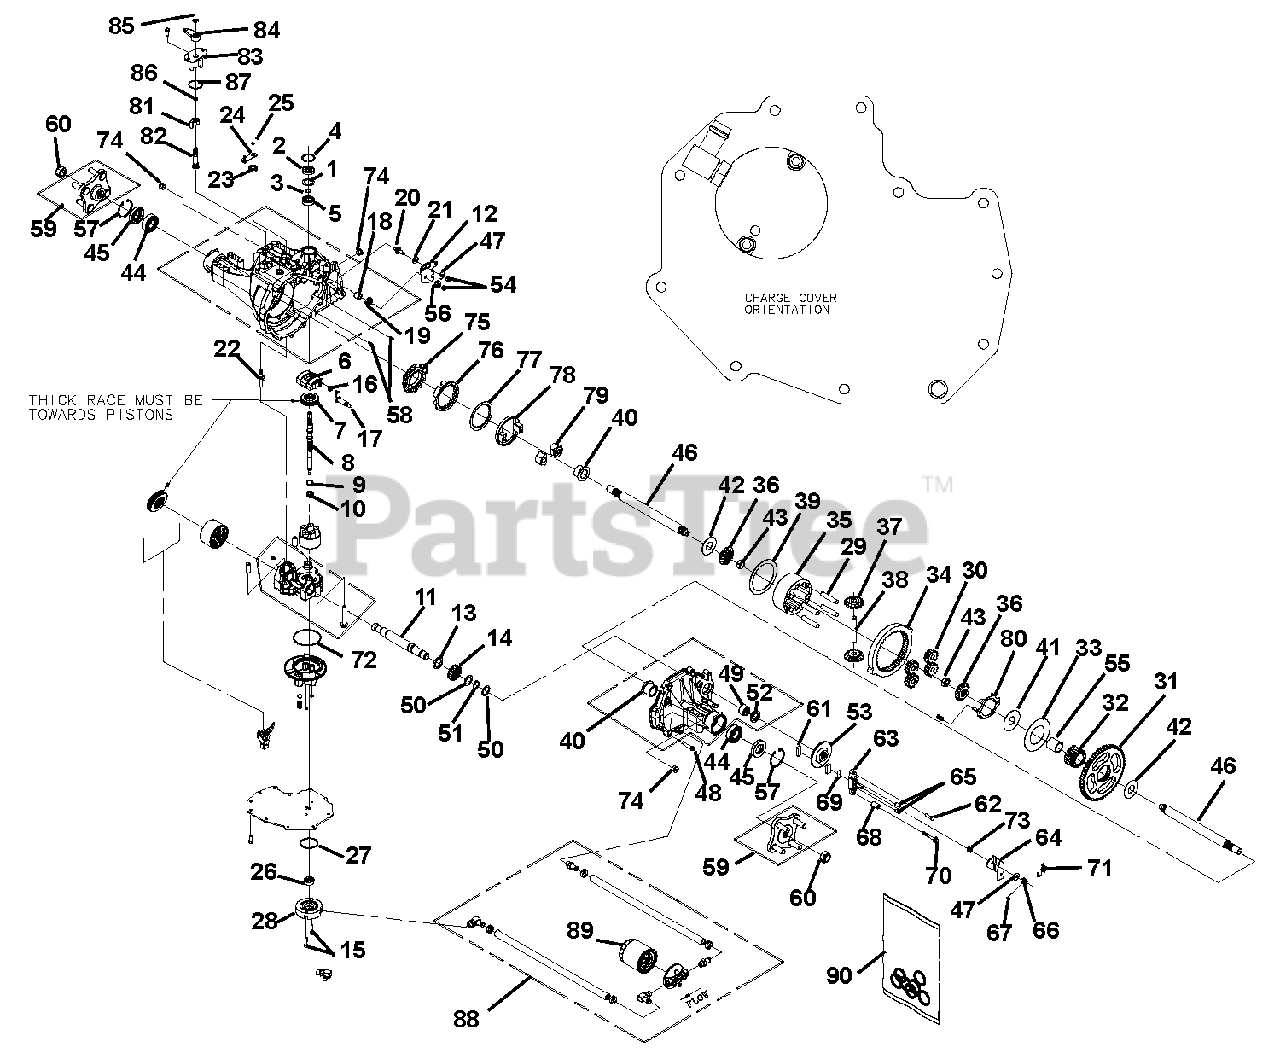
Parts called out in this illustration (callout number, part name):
1	Spacer, .98 x 1.37 x .04
2	Seal, Lip 15 x 35 x 7
3	Ring, Wire Retaining
4	Ring, Retaining
5	Bearing, Shaft Ball
6	Swashplate, Variable
7	Bearing, Thrust 30 x 52 x 13
8	Shaft, Input (STD Charge)
9	Washer, Thrust .59 x .79 x .04
10	Spring, Block
11	Shaft, Motor
12	Arm, Control
13	Spacer, 1.03 x 1.38 x .184
14	Gear, 16T Pinion
15	Screw, Gap M6 x 1 x 25
16	Guide, Slot
17	Arm, Trunnion Tapered Square
18	Bearing, Trunnion
19	Seal, Lip 12 x 25 x 7
20	Stud, Short 5/16-24
21	Pack, Friction
22	Actuator, Bypass
23	Seal, Lip
24	Arm, Bypass
25	Ring, Retaining
27	O-Ring, 1.862 x 2.068
28	Housing, External Charge Pump
29	Pin, Carrier
30	Gear, 15T Planet
31	Gear, 57T Spur
32	Gear, 21T Sun
33	Washer, Thrust 2.32 x 4.10 x .05
34	Gear, 51T Ring
35	Carrier, Planetary
36	Gear, 14T Miter (Splined)
37	Gear, 14T Miter (Unsplined)
38	Shaft, Differential
39	Washer, Thrust 3.46 x 4.39 x .05
40	Bearing, Flange 1.0 x 1.376 x .99
41	Washer, 1.008 x 2.60 x .038
42	Washer, 1.0 x 2.25 x .04
43	Nut, Hex 5/8-18 with Patch
44	Bearing, Ball 25.4 x 52 x 15
45	Seal, Lip 1.0 x 2.049 x .375
46	Shaft, Axle 1.0 x 12.40 (30 O Splined)
47	Washer, .34 x .88 x .06
48	Screw, Torx Head 5/16-18 x 1.5
49	Bearing, Needle .875 x 1.125 x .75
50	Washer, Flat .88 x 1.25 x .04
51	Ring, Retaining
52	Seal, Lip .875 x 1.375 x .250
53	Disk, Brake
54	Nut, Hex Lock 5/16-24 w/Nylon Insert
55	Bushing, Sleeve 1.0 x 1.3 x 1.34
56	Spacer, Trunnion
57	Ring, Retaining
58	Pint Standard Headless
59	Kit, Hub Assembly
60	Nut, Hex Lock .75-16
61	Puckt Brake
62	Bolt, Hex Head 1/4-20 x 1 W/Patch
63	Assembly, Brake Yoke
64	Arm, Brake
65	Pint Brake Actuating
66	Nut, Castle 5/16-24
67	Pin, Cotter 3/32 x .75
68	Spacer, .26 x .57 x .87
69	Plate, Puck
70	Bolt, Hex Head 1/4-20 x 2 W/Patch
71	Spring, Brake Arm BIAS
72	O-Ring, 2.987 x 3.09
73	Spring, CAMP. Brake Anti-Drag
74	Plug, Steel (with Seal)
75	Cam, Stationary
76	Cam, Rotating
77	Washer, Thrust 2.78 x 3.60 x .036
78	Plate, Load
79	Dog, Engagement
80	Plate, Guide
81	Cam, Differential Lock Actuating
82	Shaft, Differential Lock Actuating
83	Sleeve, Differential Lock Actuating
84	Arm, Differential Lock Actuating
85	Ring, Retaining
86	O-Ring, .364 x .504
87	O-Ring, 1.489 x 1.629
88	KIit, Filter Assembly
90	Kit, Seal and O-Ring
